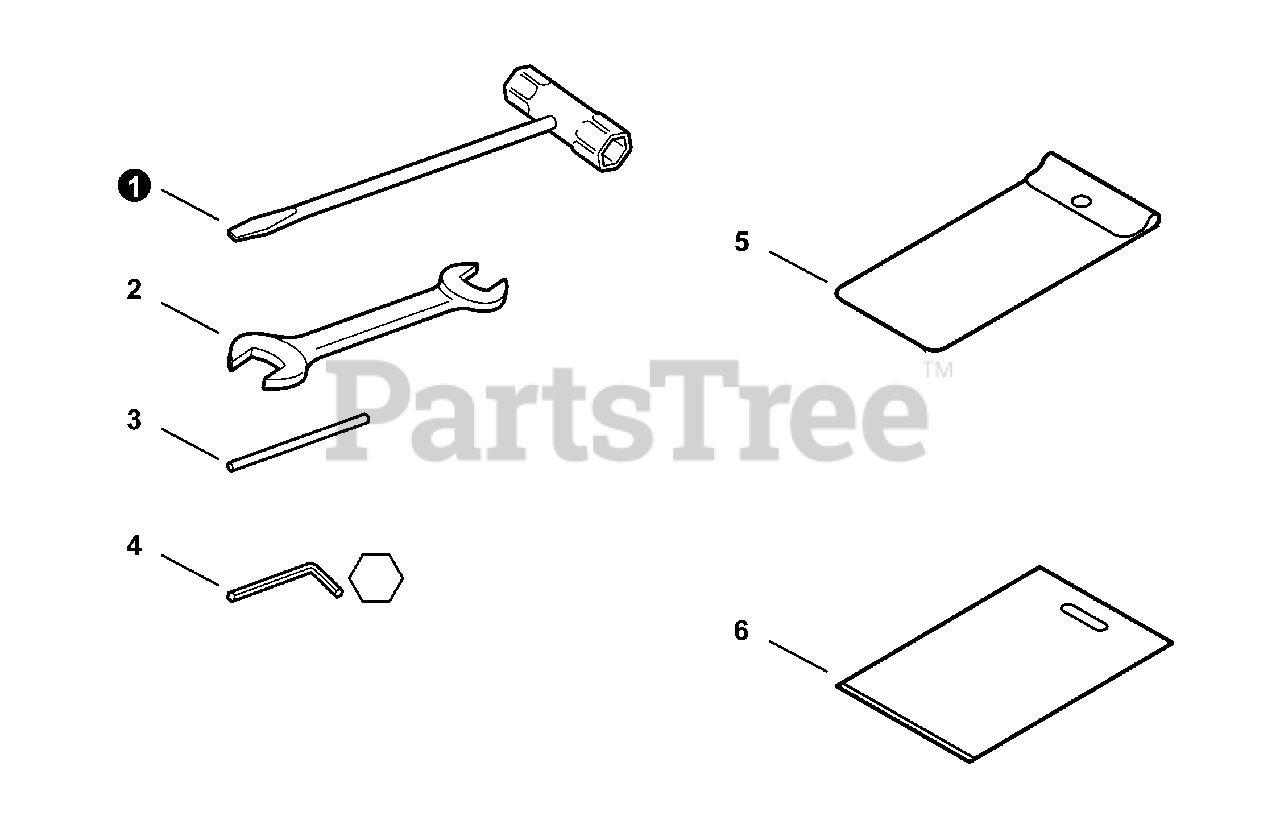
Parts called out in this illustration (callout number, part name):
1	T-WRENCH 17×19 L200
2	SPANNER 8×10
3	TOOL, LOCKING 5×120 MM
4	WRENCH, ALLEN 4 MM
5	BAG, TOOL
6	CASE, TOOL
